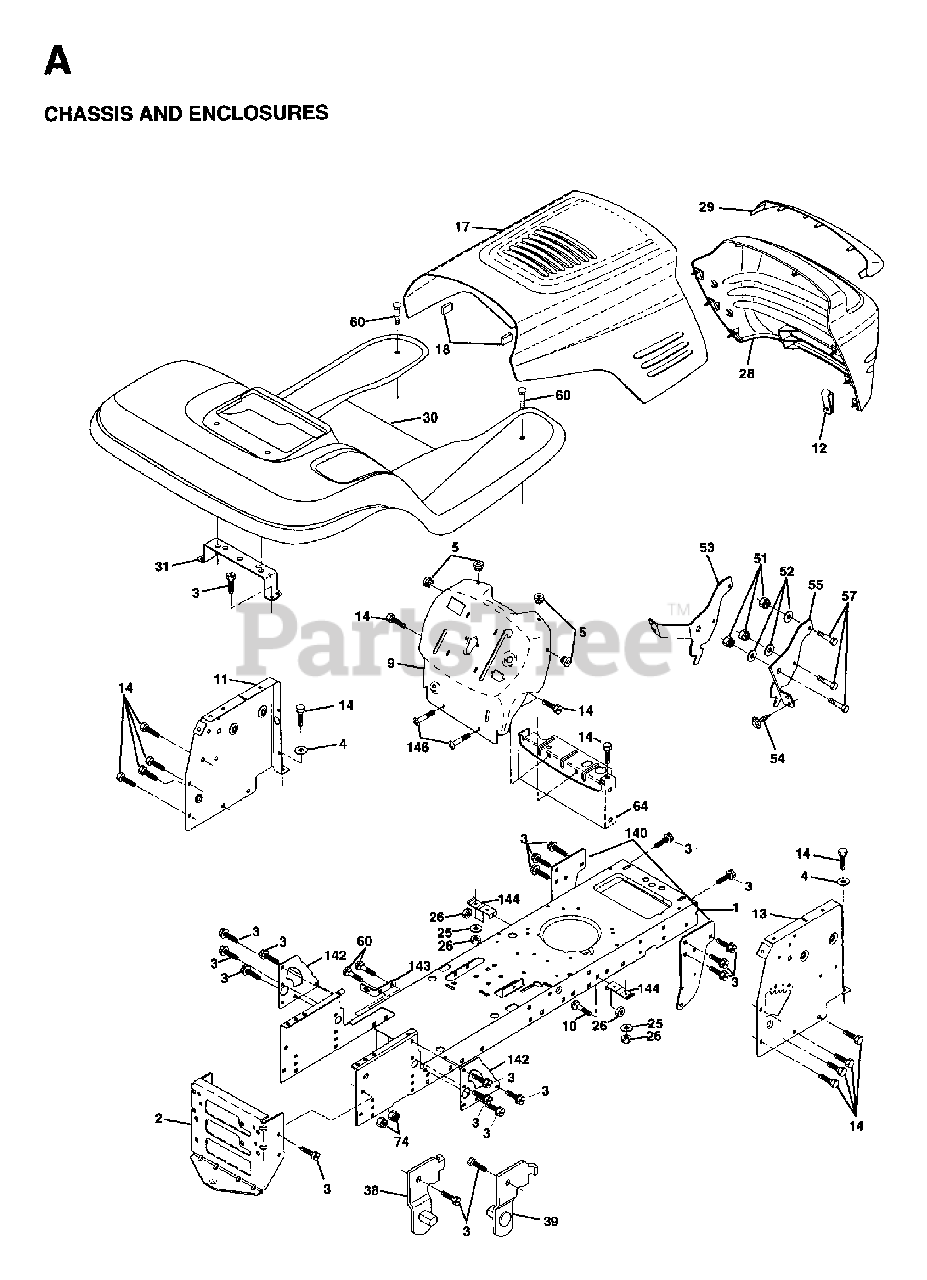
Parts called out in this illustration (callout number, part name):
1	CHASSIS WELDMENT
2	STRETCH DRAWBAR
3	SCREW
9	BOLT D
10	BOLT D
11	PANEL PNT DASH LH
13	PANEL DASH RH
20	PLATE MTG
23	GROMMET T
25	WASHER
26	NUT
38	BRACKET LH PIVOT
39	BRACKET RH PIVOT
51	LOCKNUT
57	BOLT
58	AIR DUCT P/L/LT
64	DASH LOWER
74	LOCKNUT
140	BRACKET CHASSIS FRONT
142	PLATE REINFORCEMENT
143	BRACKET, SWAY BAR
144	BRACKET FOOTREST
145	AXLE, BRACE
146	SCREW TORX HD 5/16X18
